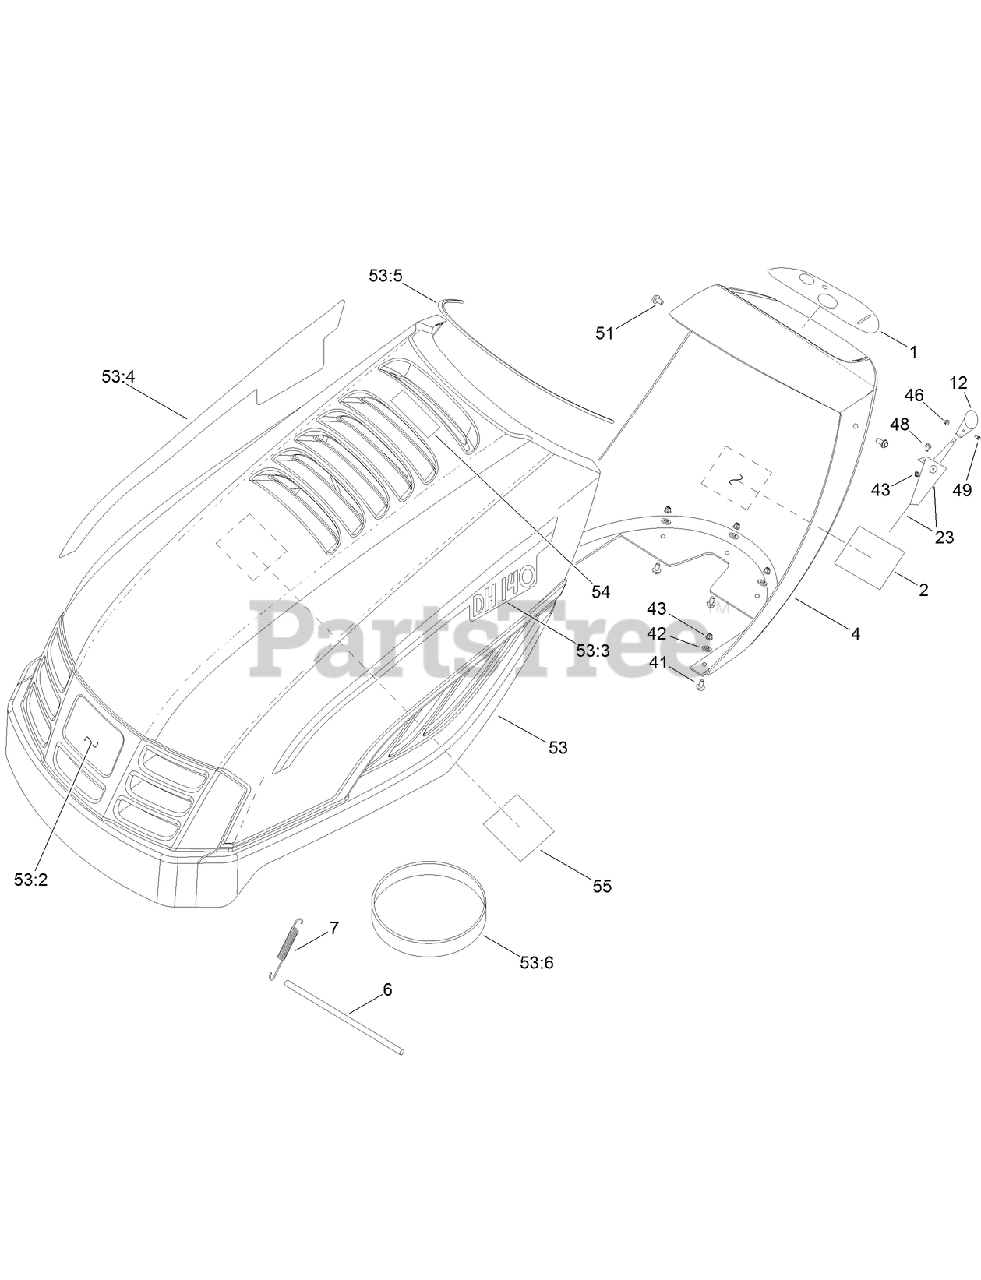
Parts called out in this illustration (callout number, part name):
1	DECAL-PANEL
4	PANEL-DASH
6	BAR-SAFETY
7	SPRING-HOOD
12	KNOB-THROTTLE/CHOKE
23	CABLE-THROTTLE/CHOKE
41	SCREW-HEX
42	WASHER-FLAT
43	NUT-LOCK
46	NUT-HEX
48	SCREW-FLAT HEAD
53	HOOD ASM
53:3	DECAL-DH 140 (LH)
53:4	DECAL-DH 140 (RH)
53:5	RUBBER-PURL
53:6	GASKET-FOAM
54	DECAL-WARNING, HOOD
55	DECAL-DANGER
